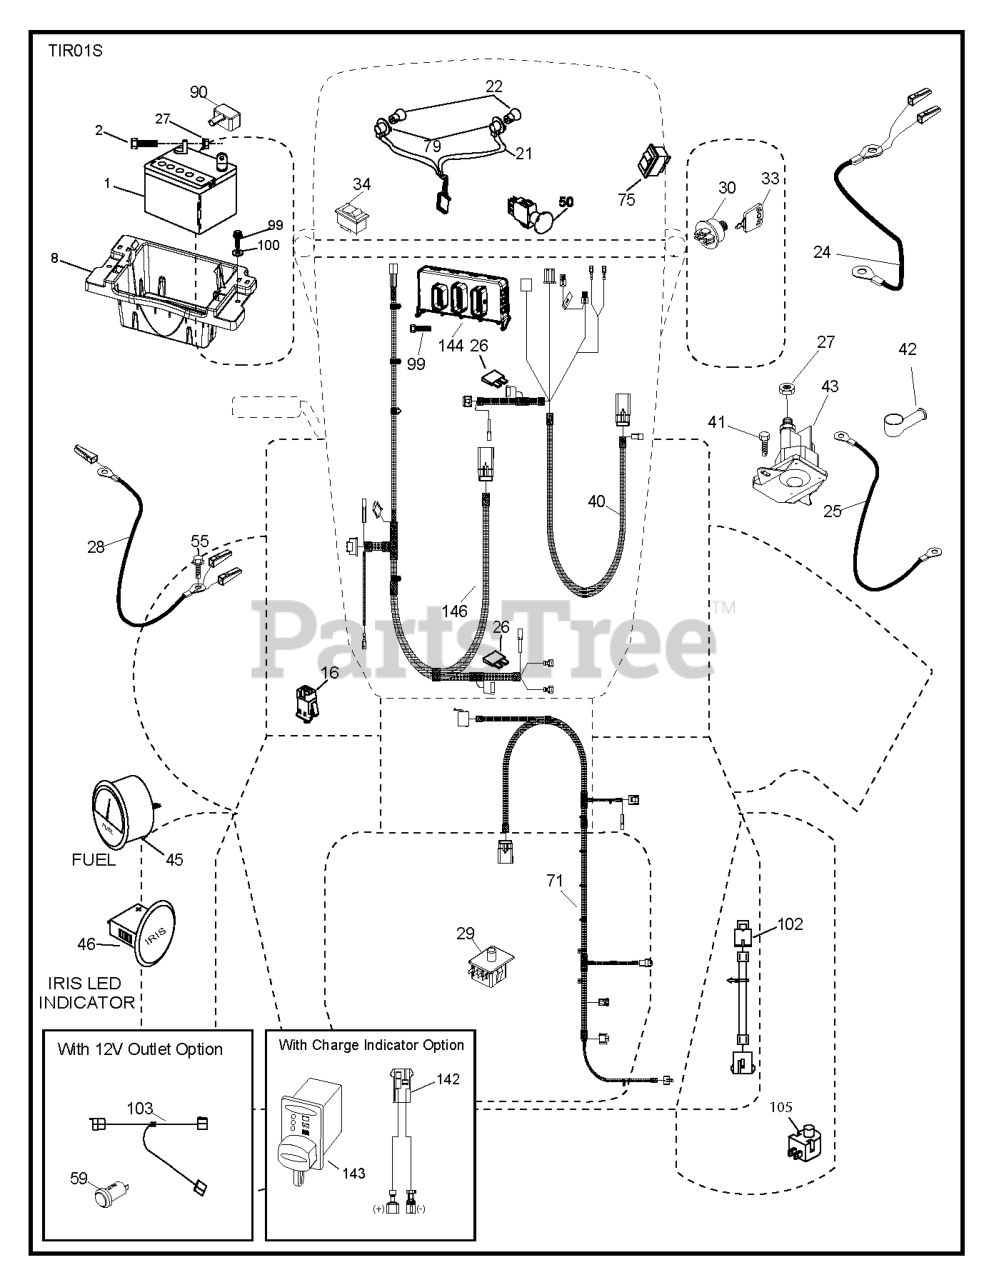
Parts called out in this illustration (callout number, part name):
1	Battery 12 Volt 25 Amp
2	BOLT.HEX.1/4.X.3/4.DICHROMATE
8	TRAY.BATTERY BOX.FRONT
16	SWITCH INTERLOOK PUSH-IN
21	HARNESS.LIGHT W/4152J BULBS
24	PRIMARY CABLE POSITIVE, TWO HA
25	CABLE.STARTER.8GA.17.5
26	FUSE 20AMP
27	NUT
28	GROUND CABLE TWO HARNESS TAPS,
29	SWITCH SEAT, 4 PIN NC/NO
30	SWITCH.IGN.DELTA.W.LGH.ROS
33	KEY.CHAIN.BLISTER.PACK.GEN.INT
40	WIRING ASSY DASH, IRIS, 300, T
41	SCREW
42	TERMINAL COVER
43	SOLENOID.STARTER.BRASS.PLUNGER
45	GAUGE.FUEL.LEVEL. ROUND.2"
46	GAUGE.6LED.IRIS.ROUND.2"
50	SWITCH.PTO.8TERMINAL.STD.BLK
55	SCREW 5/16"
71	WIRING ASSY CHASSIS, IRIS, 300
75	SWITCH.ON/OFF.(DIFF.LOCK)
79	BULB HOLDER ASM.
90	COVER.TERMINAL.BATTERY
99	SCREW HEXWSHR 1/4-20X3/4
100	WASHER
102	HARNESS PIGTAIL PCH TEX ROS
105	REVERSE SWITCH
144	CONTROL.UNIT.RIDE.ON.IRIS.BASE
146	WIRING ASSY ENGINE, IRIS, 300,
